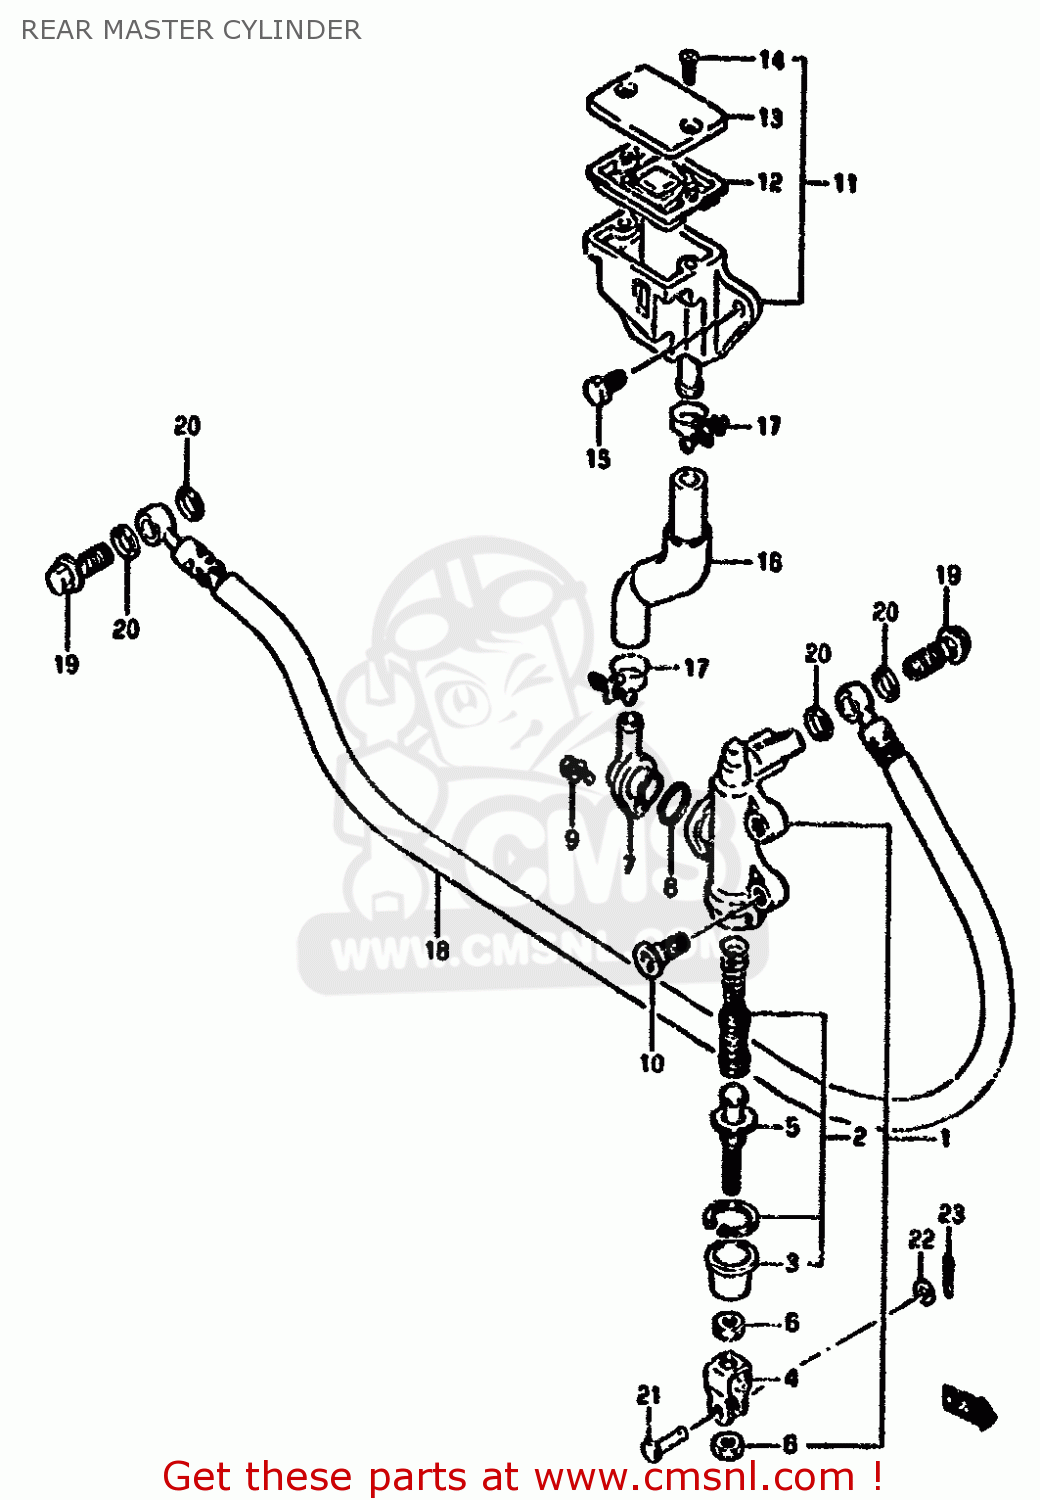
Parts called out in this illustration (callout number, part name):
1	CYLINDER ASSY,RR MASTER
2	PISTON/CUP SET
3	BOOT
4	YOKE
5	ROD,PUSH
6	NUT
7	CONNECTOR
8	O RING
9	SCREW
10	BOLT(8X15)
11	TANK ASSEMBLY,RESERVOIR
12	DIAPHRAGM
13	CAP
14	SCREW
15	BOLT
16	HOSE,RESERVOIR TANK
17	CLAMP
18	HOSE,REAR BRAKE
19	BOLT UNION
20	WASHER(10X15X1.5)
21	PIN
22	WASHER
23	PIN
